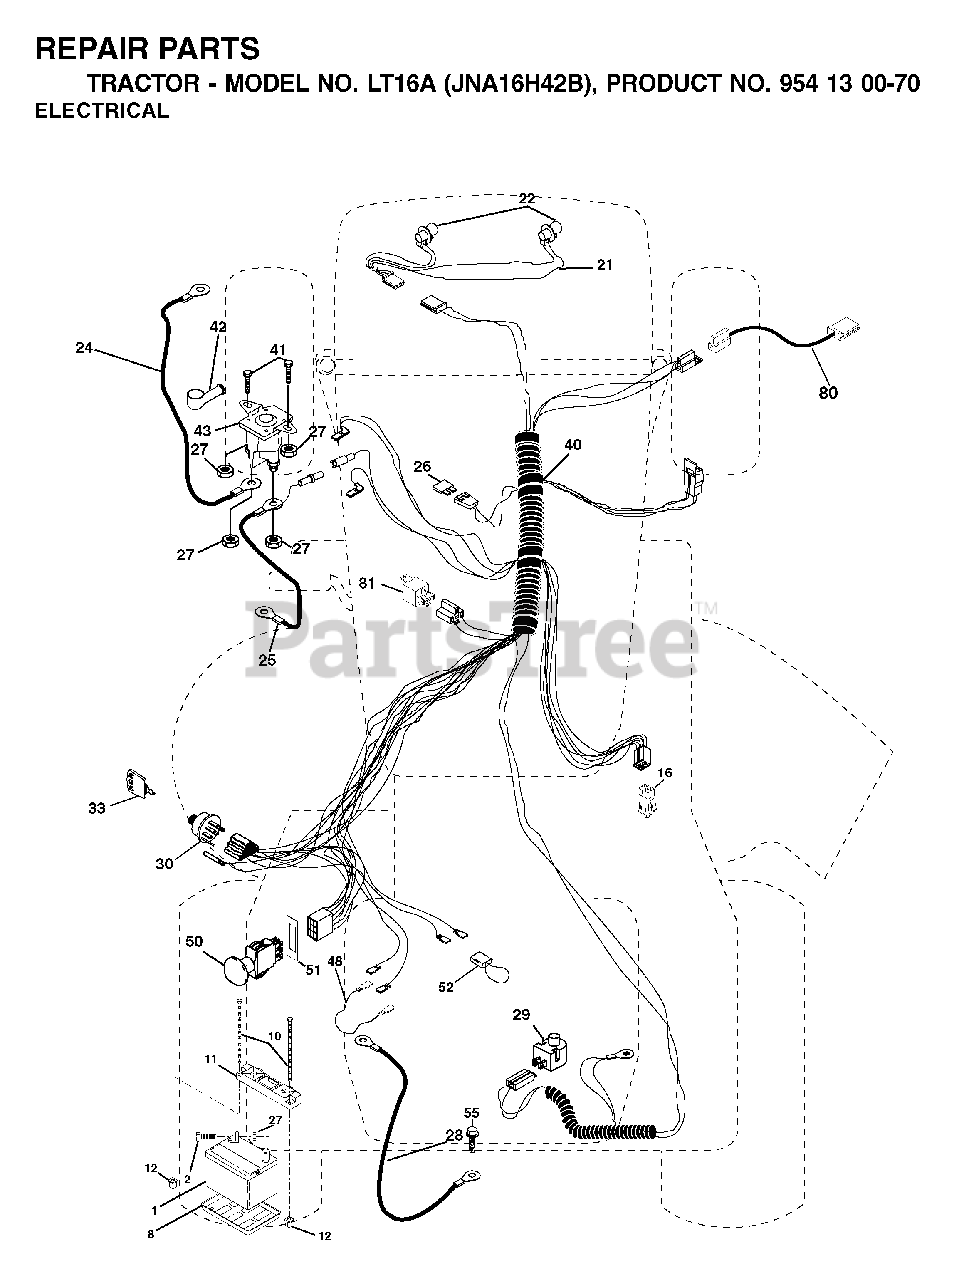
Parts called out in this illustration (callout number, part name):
1	REPL BY 532 12 38-99
8	BATTERY TRAY T
10	BOLT 1/4-20 X 7.5
11	BATTERY HOLDDOWN
12	NUT, PUSH NYLON 1/4" BATTERY
16	SWITCH INTERLOOK PUSH-IN
21	WIRE HARNESS
22	LIGHTBULB
24	BATTERY CABLE GT
25	CABLE BATTERY 6 GA 22" W/16W
26	FUSE 20AMP
27	NUT
28	CABLE GROUND 6 GA 21" 90T BLK
29	PLUNGER SWITCH (COLOR:OLIVE)
30	IGNITION SWITCH
33	KEY MLD GEN DELTA
40	IGNITION HARNESS
42	TERMINAL COVER
43	SOLENOID
50	PTO SWITCH
51	RETAINING RING
52	WIRE PROTECTION LOOP
80	HARNESS, CLUTCH
81	RELAY.ASSY.T
